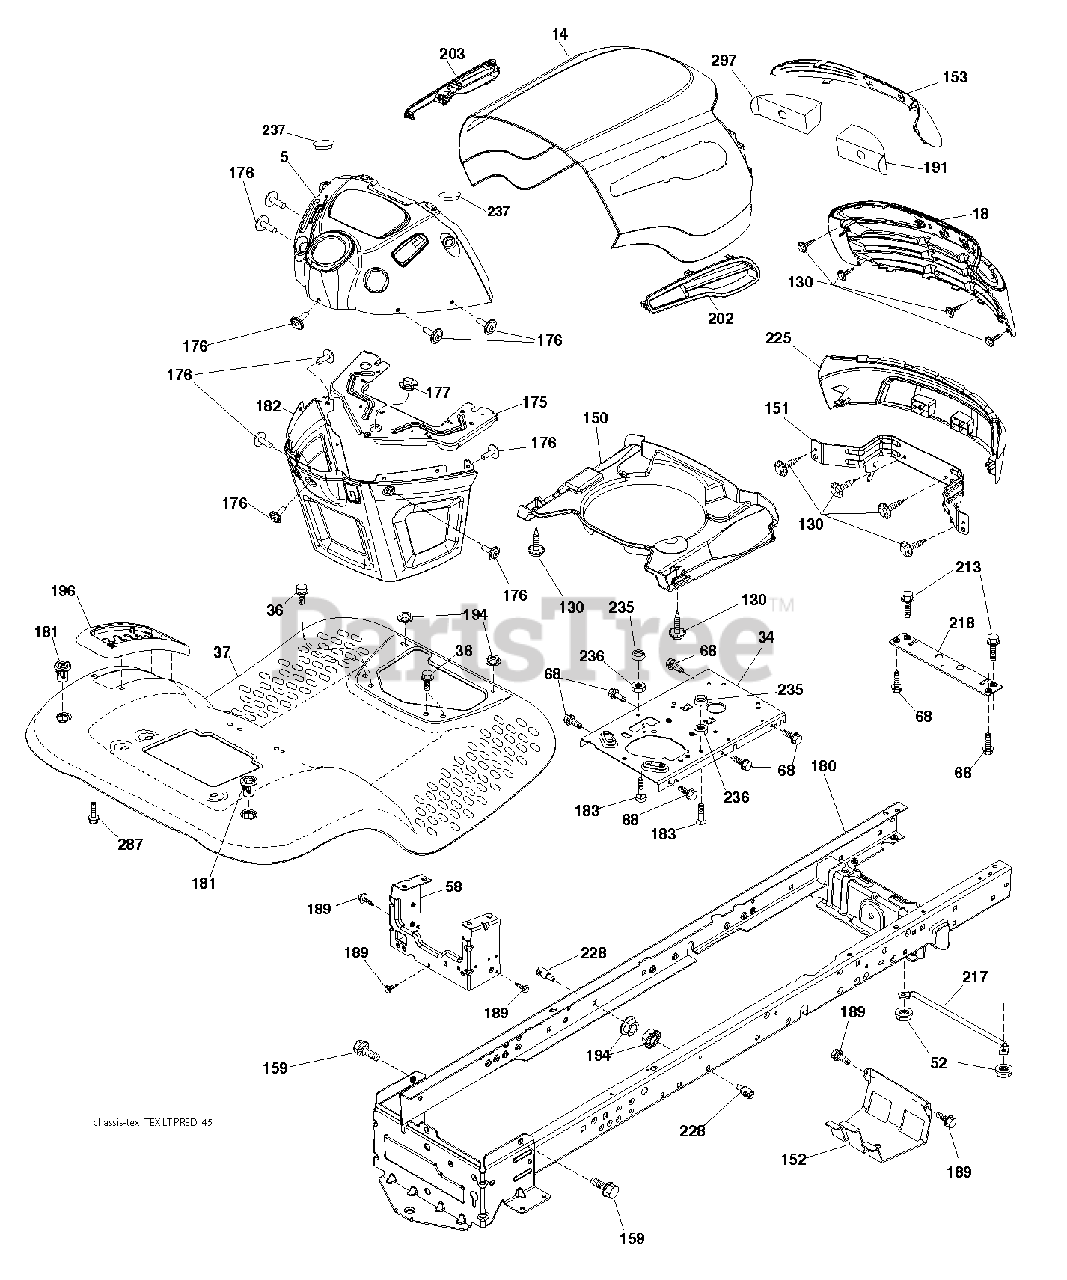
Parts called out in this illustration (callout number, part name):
34	PLATE.ENGINE.WELDED.CHASSIS
36	SCREW 5/16"
52	LOCKNUT
58	DRAWBAR UPPER 2PC SMALL FENDER
130	SCREW.#10 X 0.750.BOS THREAD
151	BRACKET.PIVOT.ALPHA.LT
152	SHIELD BROWNING
159	SCREW, 3/8-16X3/4
175	CROSSMEMBER
176	SCREW.#10-24X5/8.RN.QU
177	BUSHING STEERING
180	CHASS.WLDMNT.TL.12GA/2P.48/54
181	FEND/FTRST.PCH.CPH.NFW
182	DASH.LWER.PREDATOR/HUSQ.LT
183	BOLT.5/16-18X1-1/4 FULL THD
189	SCREW
191	INSERT.REFLECT.PREDATOR.LT.RH
194	NUT LOCK HEX FLANGE 5/16-18
196	CONSOLE.ASM.DECKLFT.BL/RBT.TLT
213	BOLT
217	ROD.PIVOT.HOOD
218	X-PIECE.HOOD.STOP.NON/
228	STUD.FASTNER.W/ANTI-ROTATE
235	SPACER FENDER
236	NUT.CENTERLOCK.5/16-
237	PLUG.MOUNT.CARGO.BLK
297	REFLECTOR.INSERT.PRED.LH.LT
